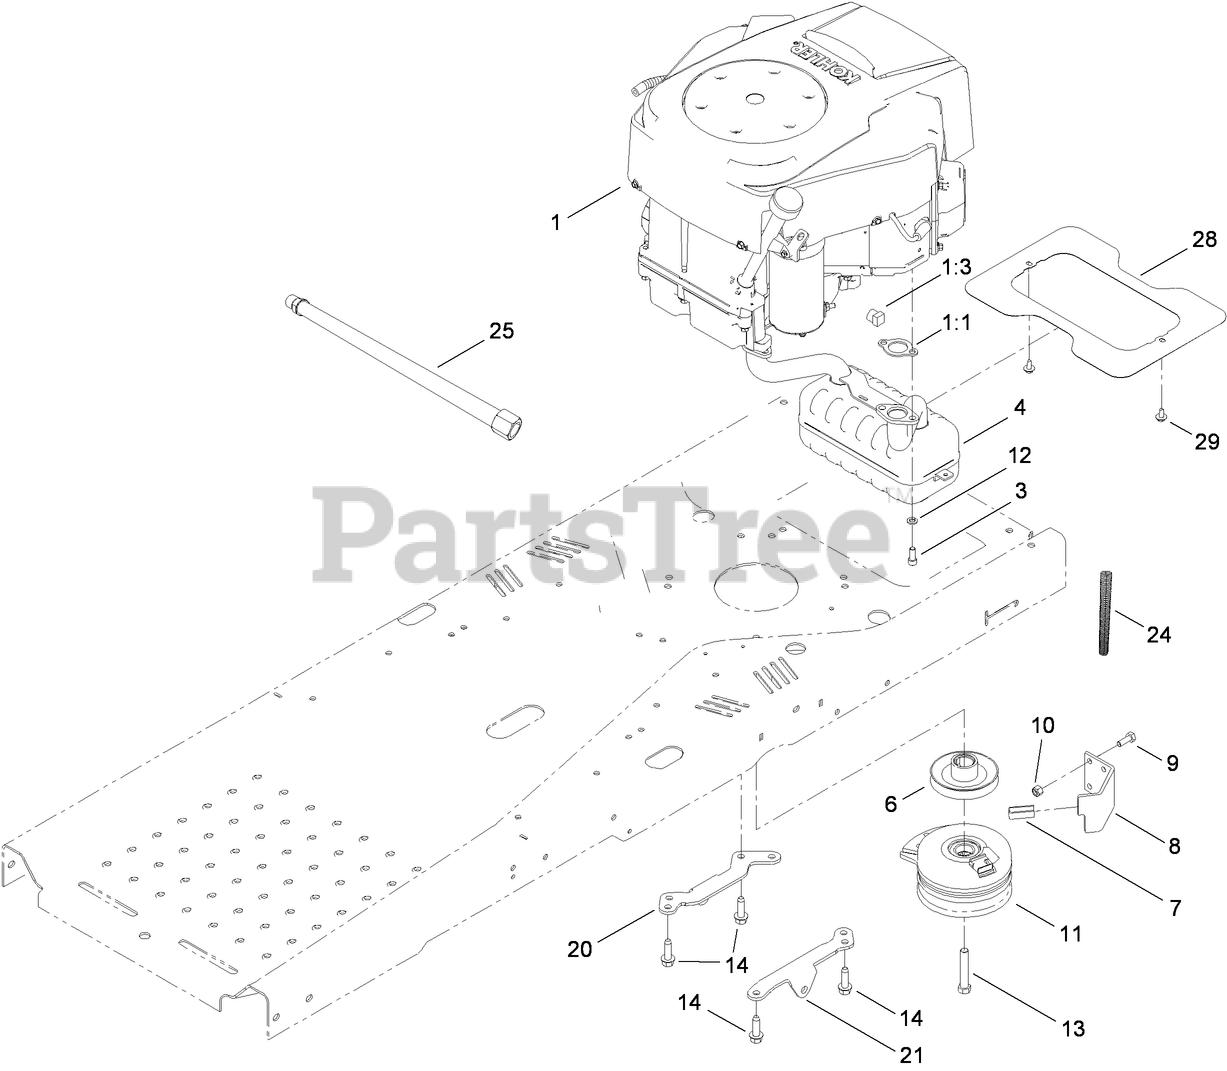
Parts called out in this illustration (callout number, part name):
1:1	GASKET-EXHAUST
1:3	PLUG-PIPE, SQH
3	SCREW-HSH
4	MUFFLER-KOHLER
6	PULLEY-ENGINE
7	BUMPER-PAD
8	STOP-CLUTCH
9	SCREW-HH
10	NUT-LOCK, NI
11	CLUTCH-ELECTRIC
12	WASHER-LOCK
13	SCREW-HH
14	SCREW-THD
20	SUPPORT-HYDRO, RH
21	SUPPORT-HYDRO, LH
24	TUBING-CONVOLUTED
25	HOSE-DRAIN, OIL
28	SHIELD-HEAT
29	SCREW-HHFTF
